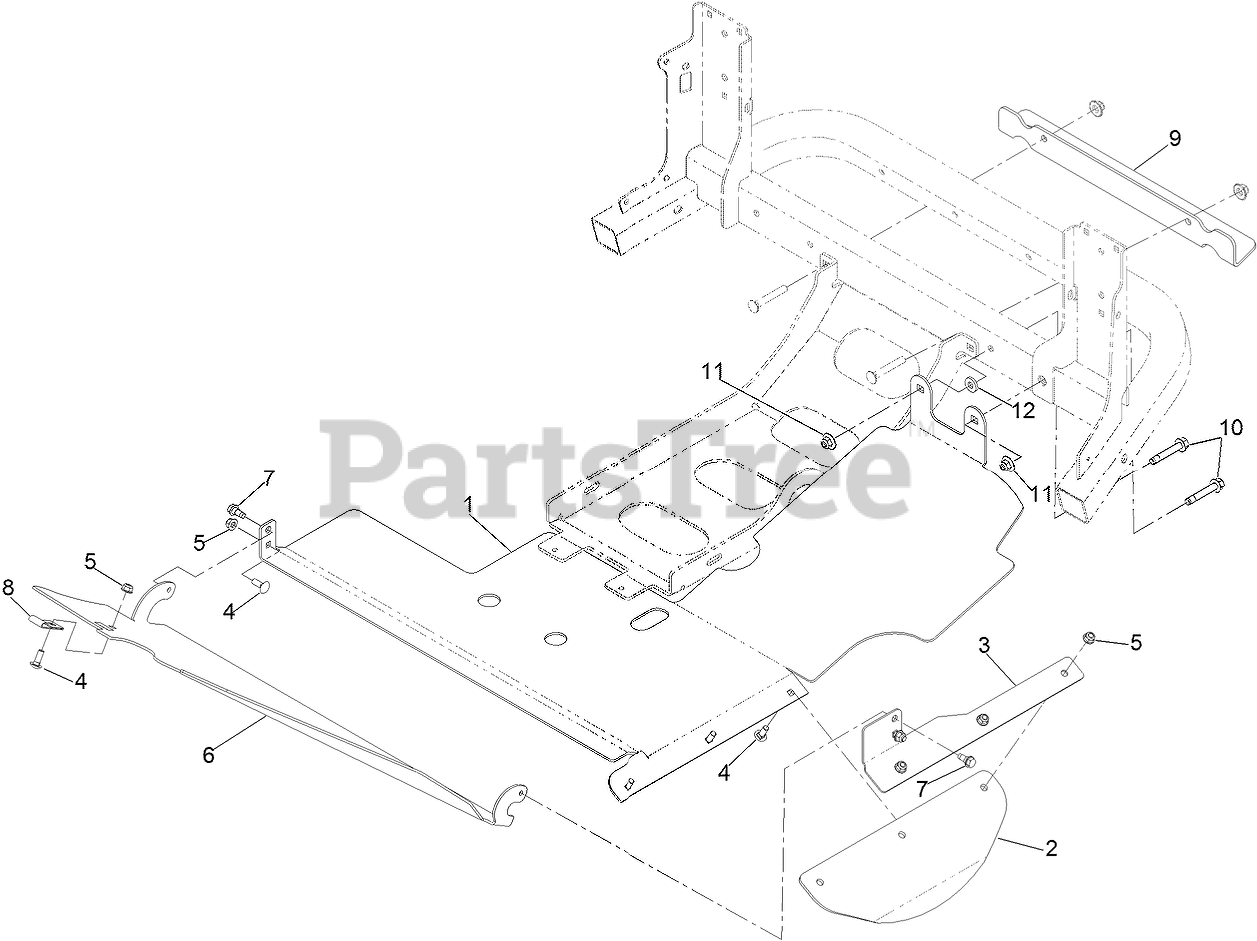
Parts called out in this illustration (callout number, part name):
1	PLATE-DISCHARGE
2	FLAP-RUBBER
3	BRACKET-FLAP, LH
4	SCREW-CARR
5	NUT-HF, NI
6	PANEL-DISCHARGE
7	SCREW-SHOULDER
8	BEARING-STRAP, NYLON
9	BRACKET-TIE DOWN
10	SCREW-HHF W/ PATCH
11	Nut-Nyloc 3/8-16 Flg
